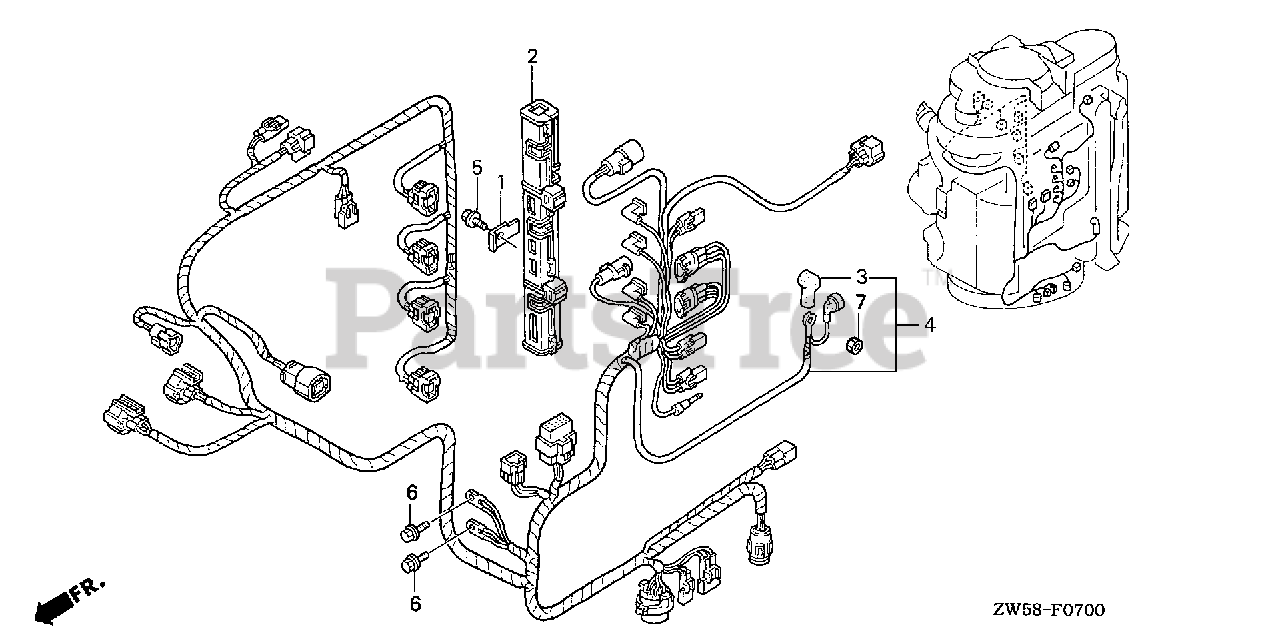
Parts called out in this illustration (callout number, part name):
1	BRACKET, CONNECTOR (C)
2	HOLDER A, HARNESS
3	COVER A, MAGNETIC SWITCH
4	CABLE ASSY., REMOTE CONTROL (A)
5	BOLT, FLANGE (6X12) (CT200)
6	BOLT, FLANGE (6X14)
7	NUT, HEX. (6MM)
